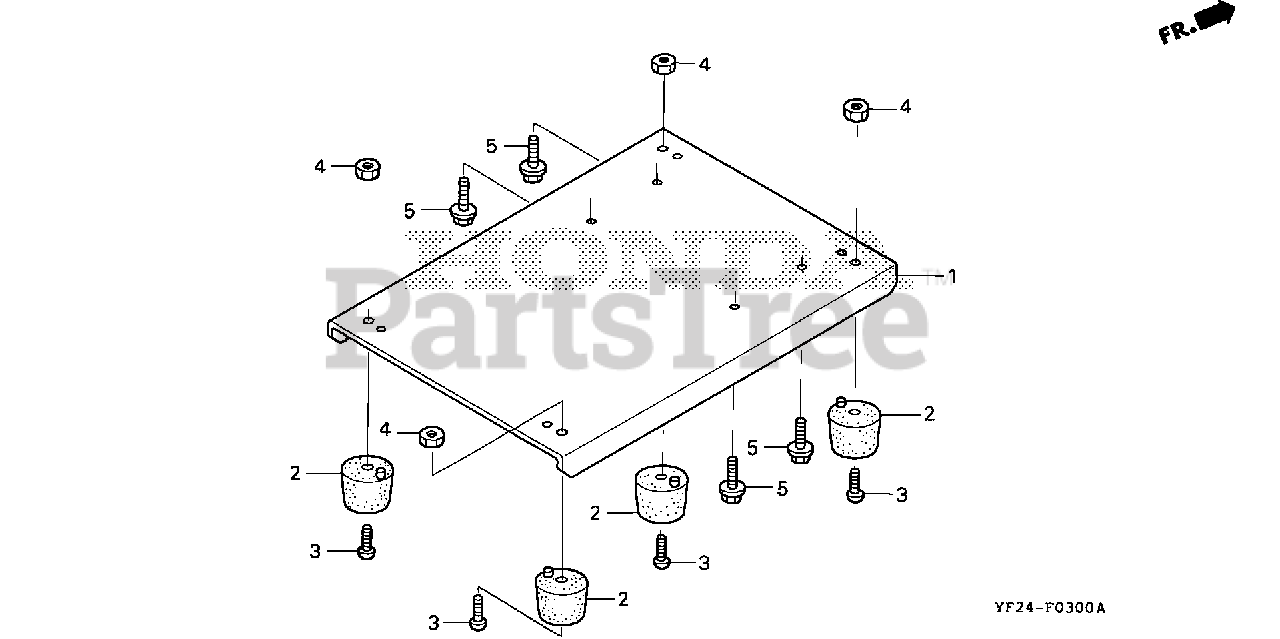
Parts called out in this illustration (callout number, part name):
1	BED, FRAME
2	RUBBER (LOWER)
3	SCREW, PAN (6X10)
4	NUT, HEX. (6MM)
5	BOLT, FLANGE (6X14)
